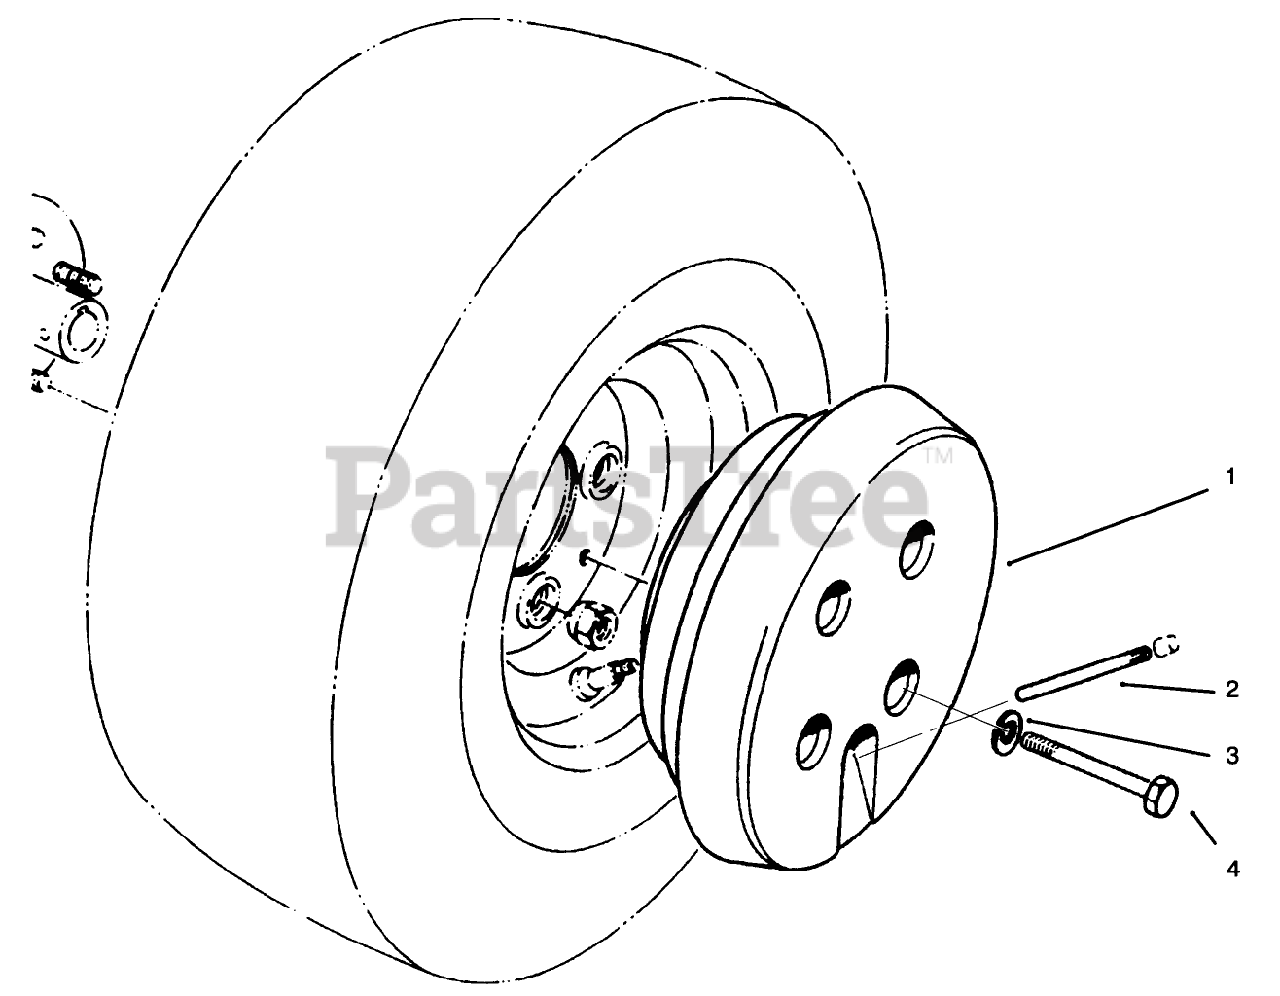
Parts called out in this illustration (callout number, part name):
1	Weight-Wheel
2	VALVE EXTENSION
3	WASHER-PLAIN
4	SCREW-HH
